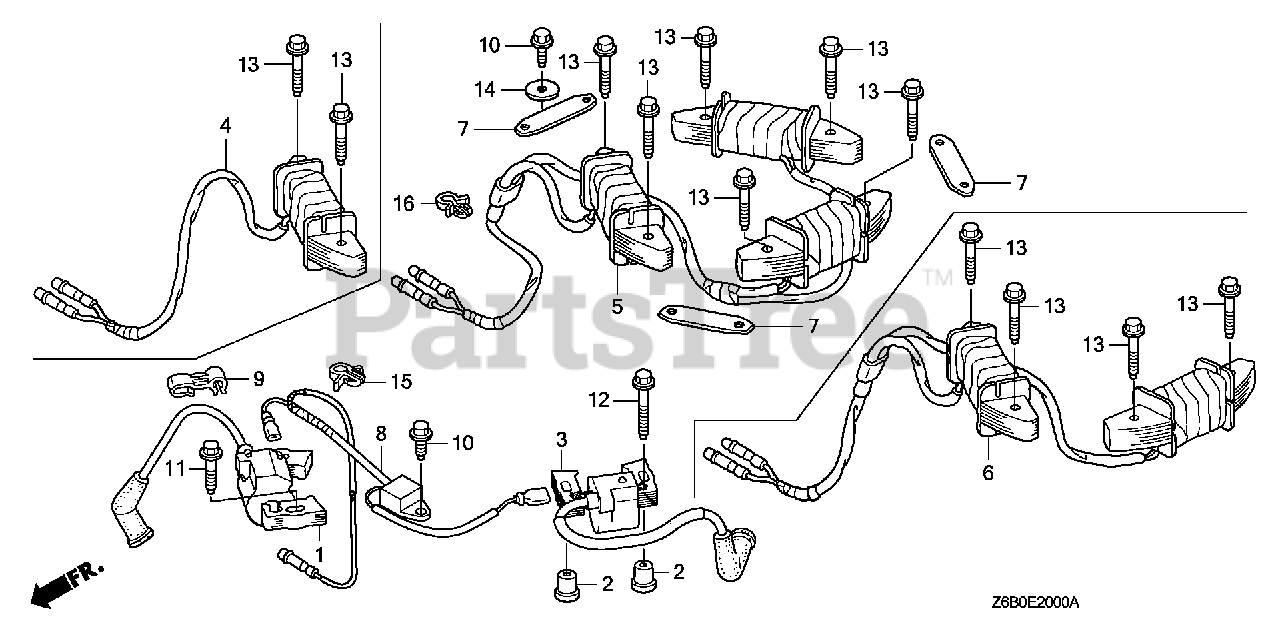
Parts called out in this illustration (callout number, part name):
1	COIL ASSY., IGNITION (#1)
2	COLLAR, IGNITION COIL
3	COIL ASSY., IGNITION (#2)
5	COIL ASSY., CHARGE (12V/18A)
8	DIODE ASSY., ENGINE STOP
9	CLAMP, CENTER CORD
10	BOLT, FLANGE (6X12) (CT200)
11	BOLT, FLANGE (6X28) (CT200) Use up to Engine SN 1530314.
12	BOLT, FLANGE (6X45)
13	BOLT, FLANGE (6X32)
14	WASHER, TANK SETTING
15	CLIP, WIRE HARNESS (6MM) (WHITE)
16	CLIP, WIRE HARNESS
